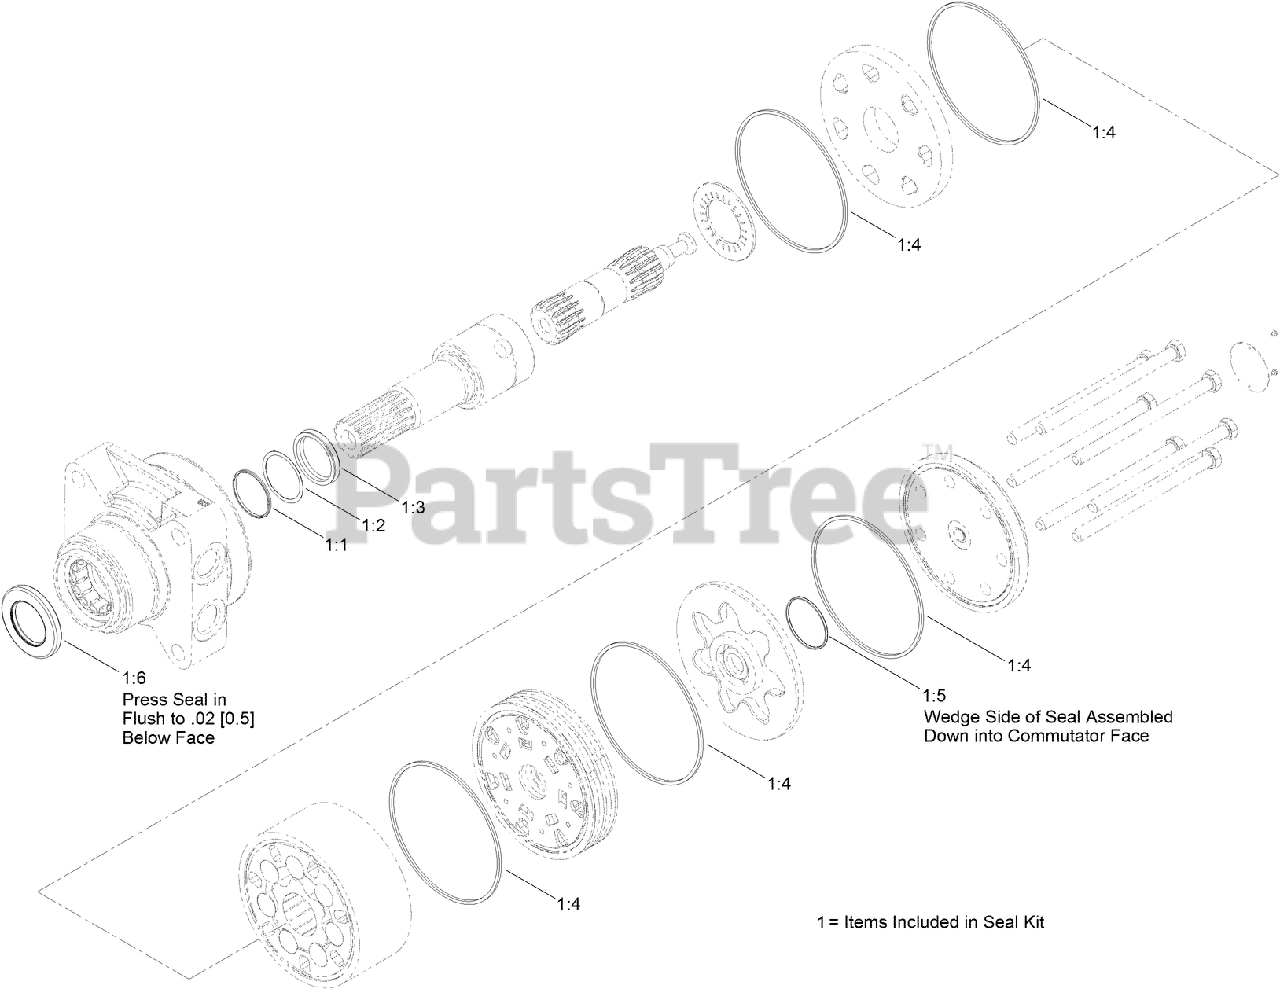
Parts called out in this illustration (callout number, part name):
1	SEAL KIT
1:1	Ring-Back Up
1:2	Washer-Back Up
1:3	SEAL-Shaft
1:4	Deck ASM
1:5	Deck ASM
1:6	Deck ASM
